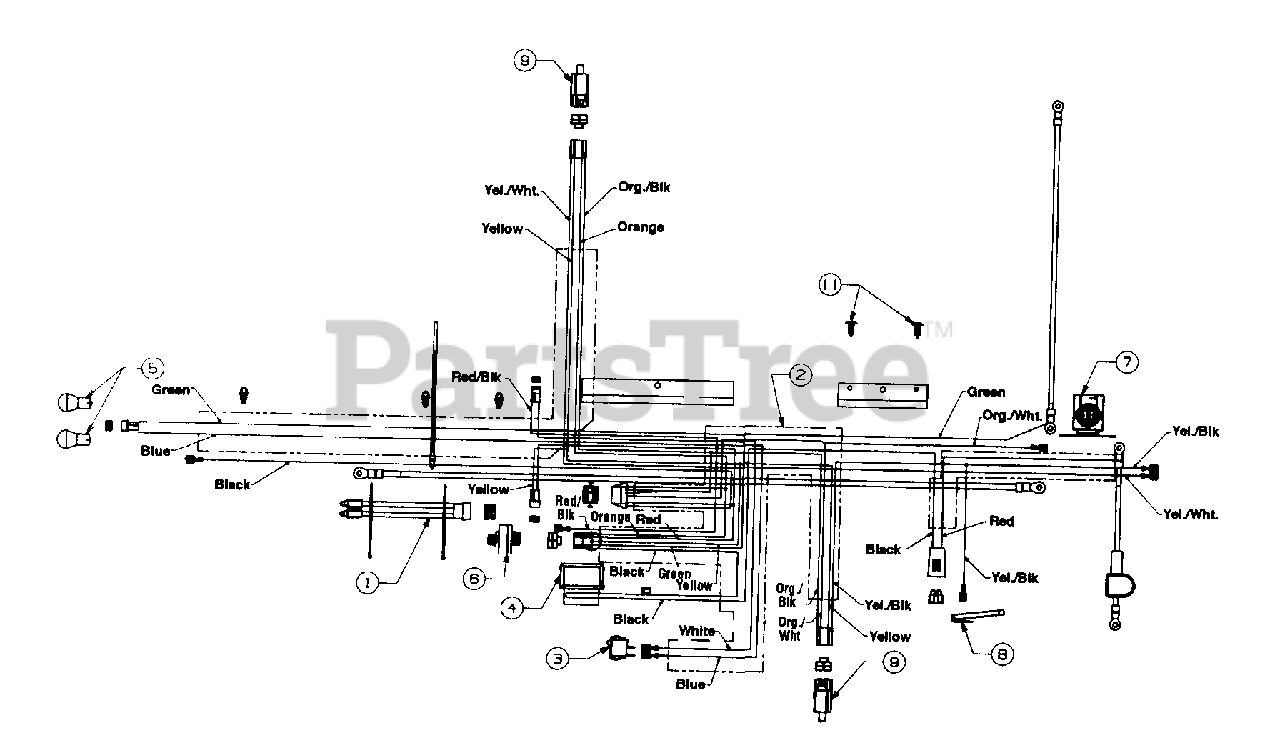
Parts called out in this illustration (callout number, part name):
1	Wire Harness (Monitor)
2	Wire Harness w/Light Switch, Amp and Monitor
3	Light Switch
4	Ammeter
5	Bulb (Headlight)
6	Ignition Switch
7	Solenoid
8	Safety Switch (Reverse)
9	Safety Switch
11	Ratchet
